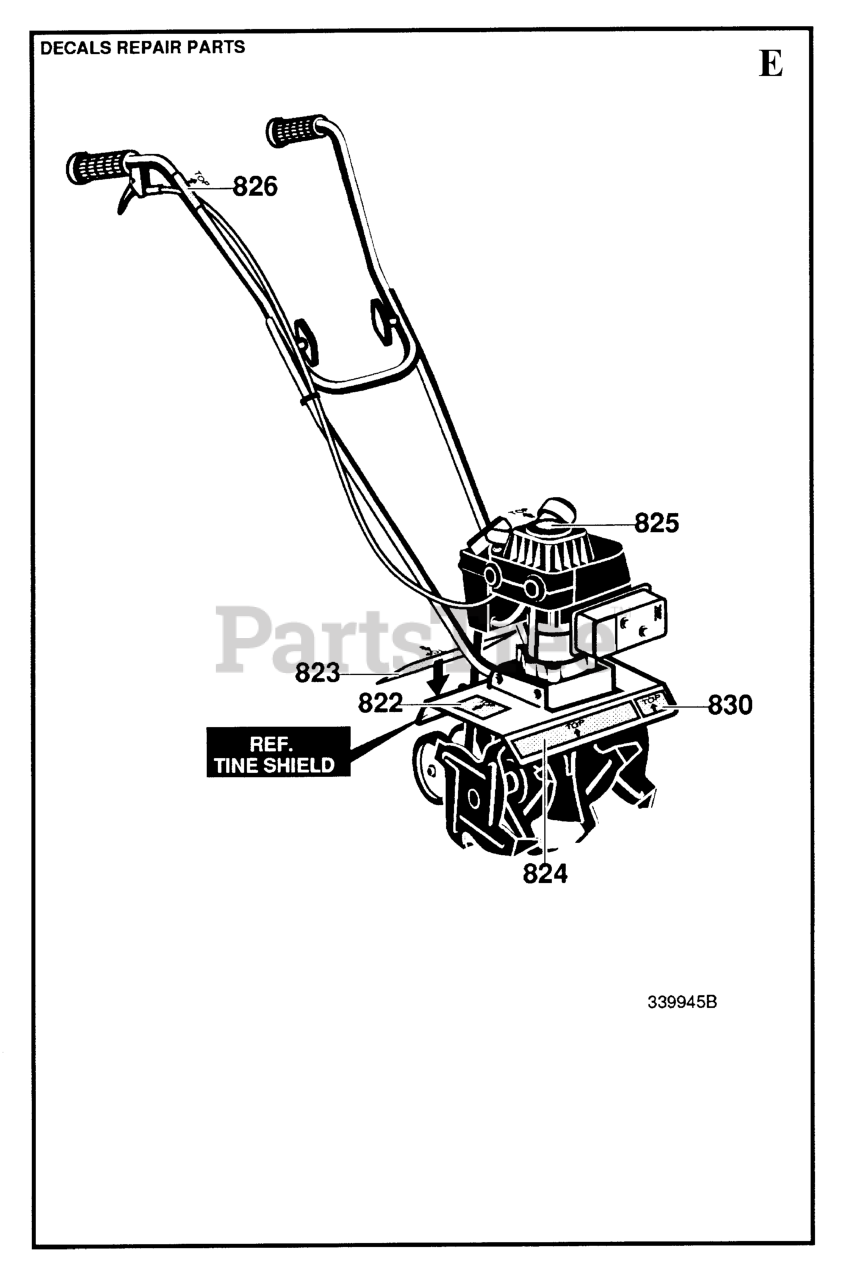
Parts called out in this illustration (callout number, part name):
2	DRAWBAR
3	SCREW 3/8-16X3/4
5	BUMPER DASH
6	PLATE
8	CLIP,INSULATOR
10	BOLT D
11	PANEL DASH LH
13	PANEL DASH RH
15	Screw, Machine, Truss Head 5/16-18 UNC x 3/4
16	NUT
17	HOOD
18	BUMPER.HOOD.TEX.HUSQVARNA
25	WASHER
26	NUT
28	GRILL.ASM.HUSQ.TG/CRD.W/TRIM
30	CONSOLE.CRD.AUTO.GRY
31	BRACKET SUPPORT FENDER
33	FOOTREST PNT LH
34	FOOTREST PNT RH
37	Screw 5/16-18 x 1/2 Hex, Self Tapping 5/16-18 x 1/2
38	BRACKET ASM PIVOT MOWER REAR
42	LENS.LH.TEX.GT.HUSQ.CL
43	LENS.RH.TEX.GT.HUSQ.CL
58	AIR.DUCT.HOOD.TEX.GT.HUSQ
69	SCREW.HI-LO.CONSOLE
89	CONSOLE.CRD.AUTO.GREY.2005
145	ROD.PIVOT.HOOD
162	BRACKET
163	BRACKET EXTEN CHASSIS RH CRD
165	RP.COVER.BATTERY.CRD.GREY
172	WASHER
175	DOOR TRAP
179	ROD PIVOT FBI
184	BRACKET.ACTUATOR.BAGGER.SRD
186	LATCH ASSY
187	WELDNUT
189	LOCKWASHER #10
190	SCREW
207	SCREW, 5/16-18 X 1/2
209	SCREW, 3/8-16X3/4
213	SKIRT.HOOD.SIDE.HUSQ.LH.GREY
214	SKIRT.HOOD.SIDE.HUSQ.RH.GREY
256	COVER FENDER CRD
263	BEZEL.RH.TEX.GT.HUSQ
264	BEZEL.LH.TEX.GT.HUSQ
265	SEALING
266	SEALING
272	VENT.SIDE.HOOD.HUSQ.RH.GREY
273	VENT.SIDE.HOOD.HUSQ.LH.GRAY
278	SCREW
295	VENT.ASM.TORPHD.HUSQGT.LOGO.CL
300	INSERT.HEX.GRILL.HUSQ.
301	INSERT.HEX.GRILL.HUSQ.GREY
302	INSERT.HEX.GRILL.HUSQ.
303	INSERT.HEX.GRILL.HUSQ.
304	SCREW 14-20 X 5/8
